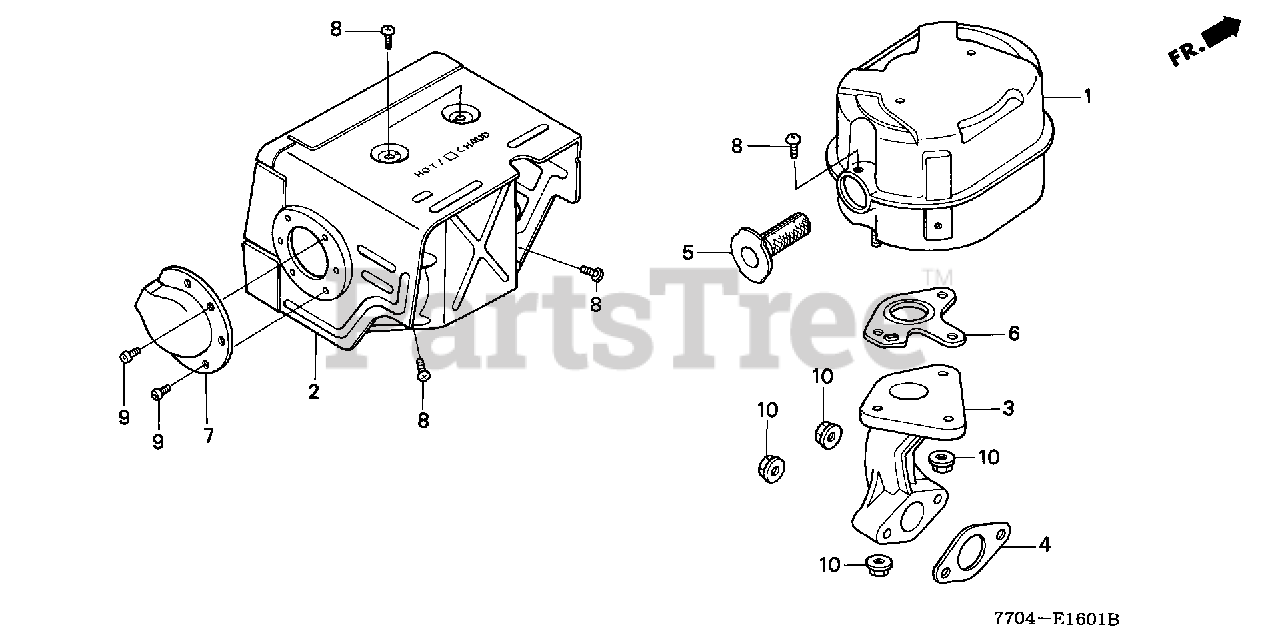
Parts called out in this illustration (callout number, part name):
2	PROTECTOR, MUFFLER (STD)
4	GASKET, EX. PIPE
5	ARRESTER, SPARK
6	GASKET, MUFFLER (ARRESTER) (NIPPON LEAKLESS)
7	DEFLECTOR, MUFFLER
8	SCREW, TAPPING (5X8)
9	SCREW, TAPPING (4X6)
10	NUT, FLANGE (8MM)
